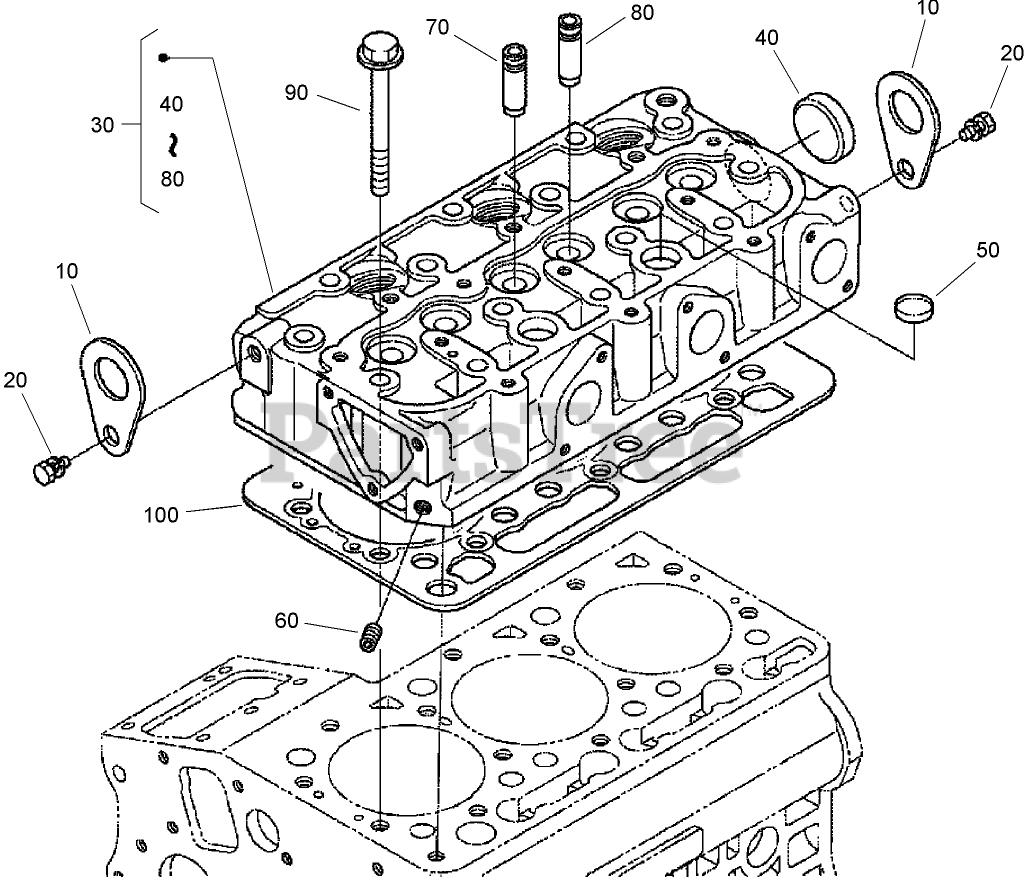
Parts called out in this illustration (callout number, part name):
10	HOOK-ENGINE
30	HEAD-CYLINDER
40	CAP-SEALING
50	CAP-SEALING
60	PLUG
70	GUIDE-VALVE, INLET
80	GUIDE-VALVE, EXHAUST
90	BOLT-HEAD, CYLINDER
100	GASKET-HEAD, CYLINDER
